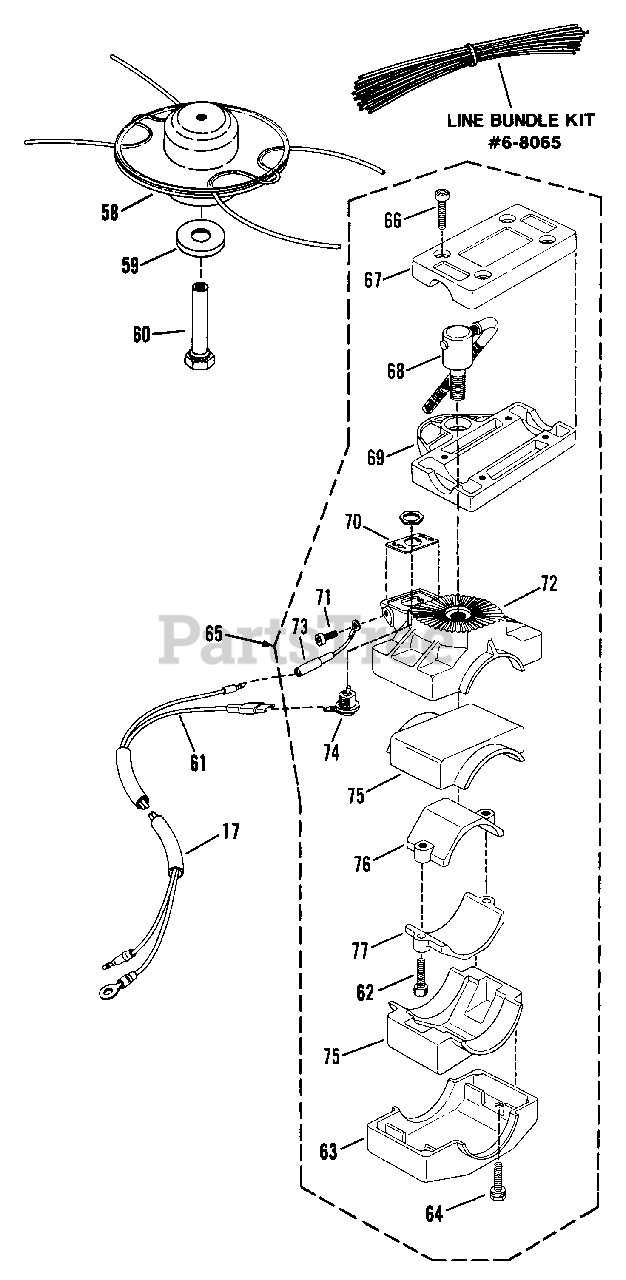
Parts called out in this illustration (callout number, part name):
6-8065	Line Bundle Kit
17	TUBE, Wire Leads
58	HEAD, Fixed Line
59	PAD, Wear
60	BOLT, Arbor
61	WIRE LEADS
62	SCREW, M6 x 25mm, ALLEN Hd.
63	JOINT, "C" Handle
64	BOLT, M6 x 30mm Hex
65	SWIVEL HANDLE ASSM'Y.
66	SCREW. M5 x 20mm. Allen Hd.
67	JOINT "A", Handle
68	LOCK HANDLE
69	JOINT "B", Handle
70	PLATE, Switch
71	SCREW, M5 x 10mm
72	JOINT "D", Handle
73	LEAD, Wire (Ground)
74	SWITCH, Stop
75	RUBBER, Vibro
76	FITTING "A", Tube
77	FITTING "B", Tube
